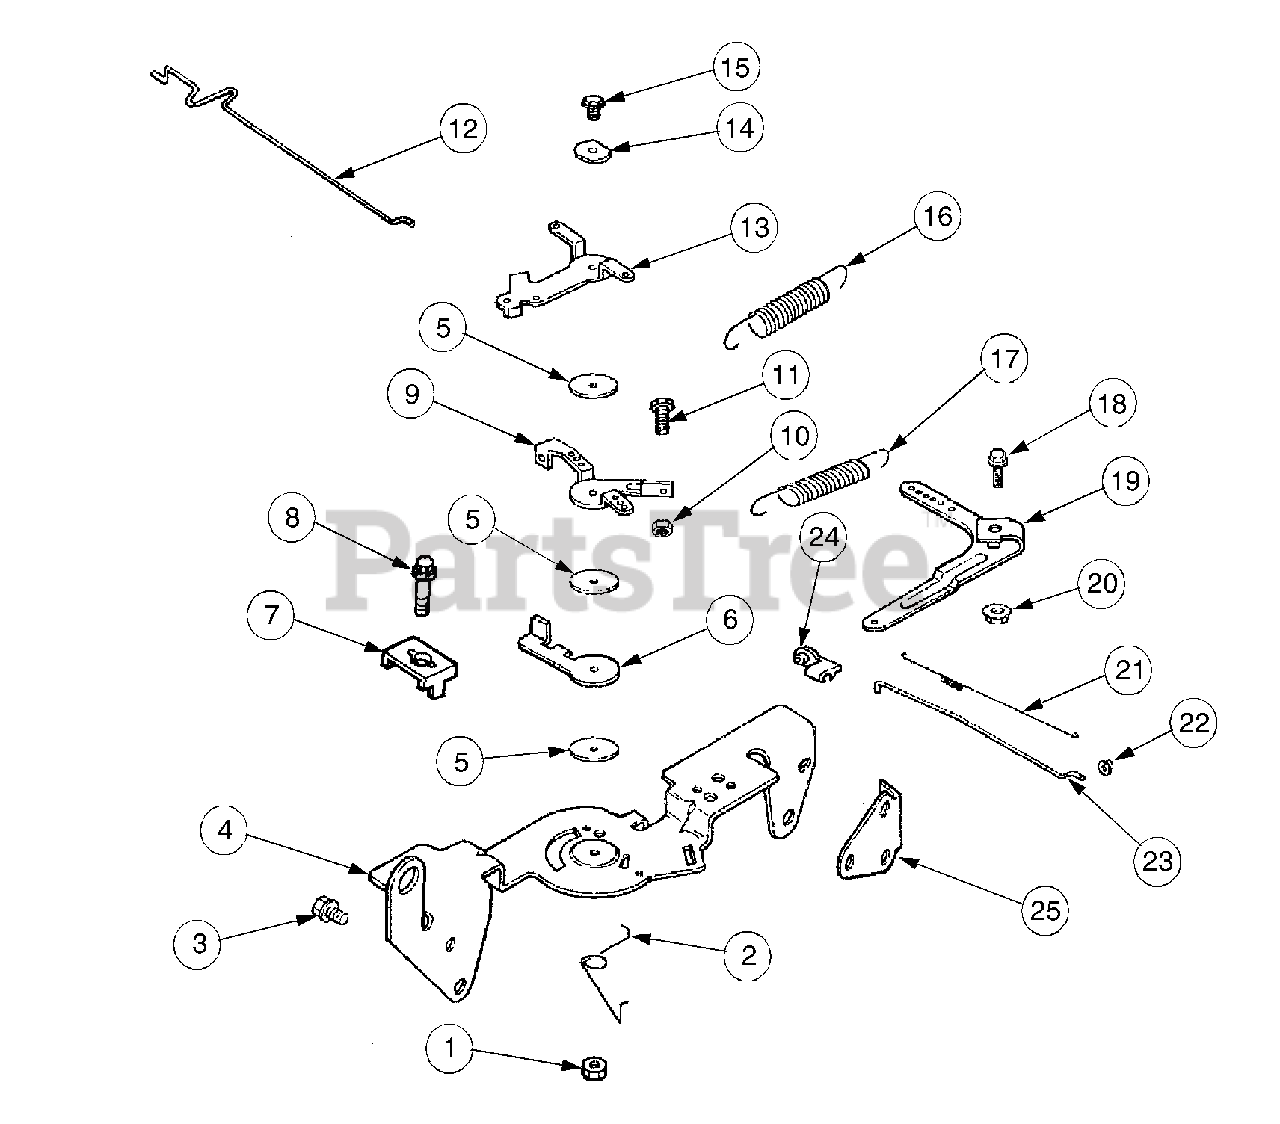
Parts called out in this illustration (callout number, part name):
1	Nut, Hex Lock M5 x 0.8
2	Spring, Choke Return
3	Screw, Hex Flange M6 x 1.0 x 16
4	Bracket, Control
5	Washer, Plain 5.5mm
6	Lever, Throttle Actuator
7	Clamp, Cable
8	Screw, Hex Flange M5 x 0 8 x 16
9	Lever, Throttle Control
10	Nut, Hex M4 x 0.7
11	Screw, Hex Cap M4 x 0.7 x30
12	Linkage, Choke
13	Lever, Choke
14	Washer, Spring 1/4"
15	Screw, Hex Flange M5 x 0,.8 x 20
16	Spring, Throttle Limiter
17	Spring, Governor (6mm)
18	Screw, Hex Flange (6mm)
19	Lever, Governor (6mm)
20	Nut, Hex Flange M6 x 1.0
21	Spring, Linkage
22	Bushing, Linkage Retaining
23	Linkage, Throttle
24	Bushing, Linkage Retaining
25	Bracket, Support
